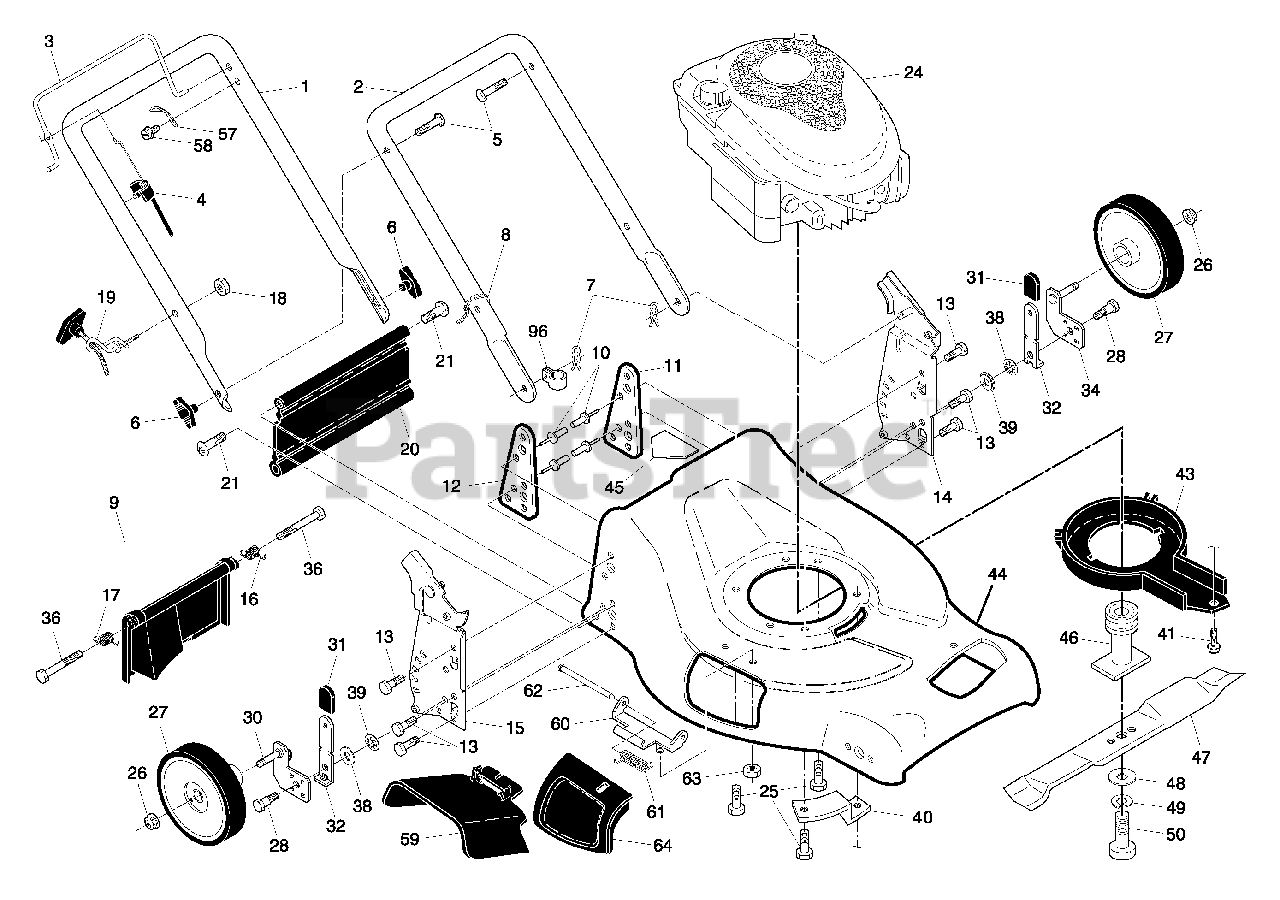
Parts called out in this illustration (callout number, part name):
1	Upper Handle
2	Lower Handle
3	Control Bar
4	Engine Zone Control Cable
5	Handle Bolt
6	Handle Knob
7	Hairpin Cotter
8	Wire Tie
9	Kit, Rear Door
10	Pop Rivet
11	Support Bracket, LH
12	Support Bracket, RH
13	Screw, Tapping 1/4-20 x 5/8
14	Handle Bracket Assembly, LH
15	Handle Bracket Assembly, RH
16	Spring, Rear Door, LH
17	Spring, Rear Door, RH
18	Nut, Hex 1/4-20
19	Rope Guide
20	Rear Skirt
21	Hinge Screw 1/4-20 x 1-1/4
25	Hex Head Thread Rolling Screw 3/8-16 x 1-1/8
26	Hex Flange Nut
27	Wheel & Tire Assembly
28	Shoulder Bolt 5/16-18 x 1-21/64
30	Axle Arm Assembly, Rear, RH
31	Selector Knob
32	Selector Spring
34	Axle Arm Assembly, Rear, LH
36	Bolt, Rear Door
38	Washer, Step 11/32 x 1-3/8 x 7/32
39	Push Nut
40	Mounting Bracket, Debris Shield
41	Screw, Debris Shield
43	Debris Shield
44	Kit, Lawn Mower Housing
45	Danger Decal
46	Blade Adapter / Pulley
47	Blade, 21"
48	Hardened Washer
49	Helical Washer
50	Hex Head Machine Screw, Grade 8, 3/8-24 x 1-3/8
57	Bracket, Upstop
58	Screw #10-24 x 1/2
59	Discharge Deflector
60	Hinge Bracket
61	Spring
62	Rod, Hinge
63	Keps Locknut 1/4-20
64	Mulcher Door
96	Clip, Cable
